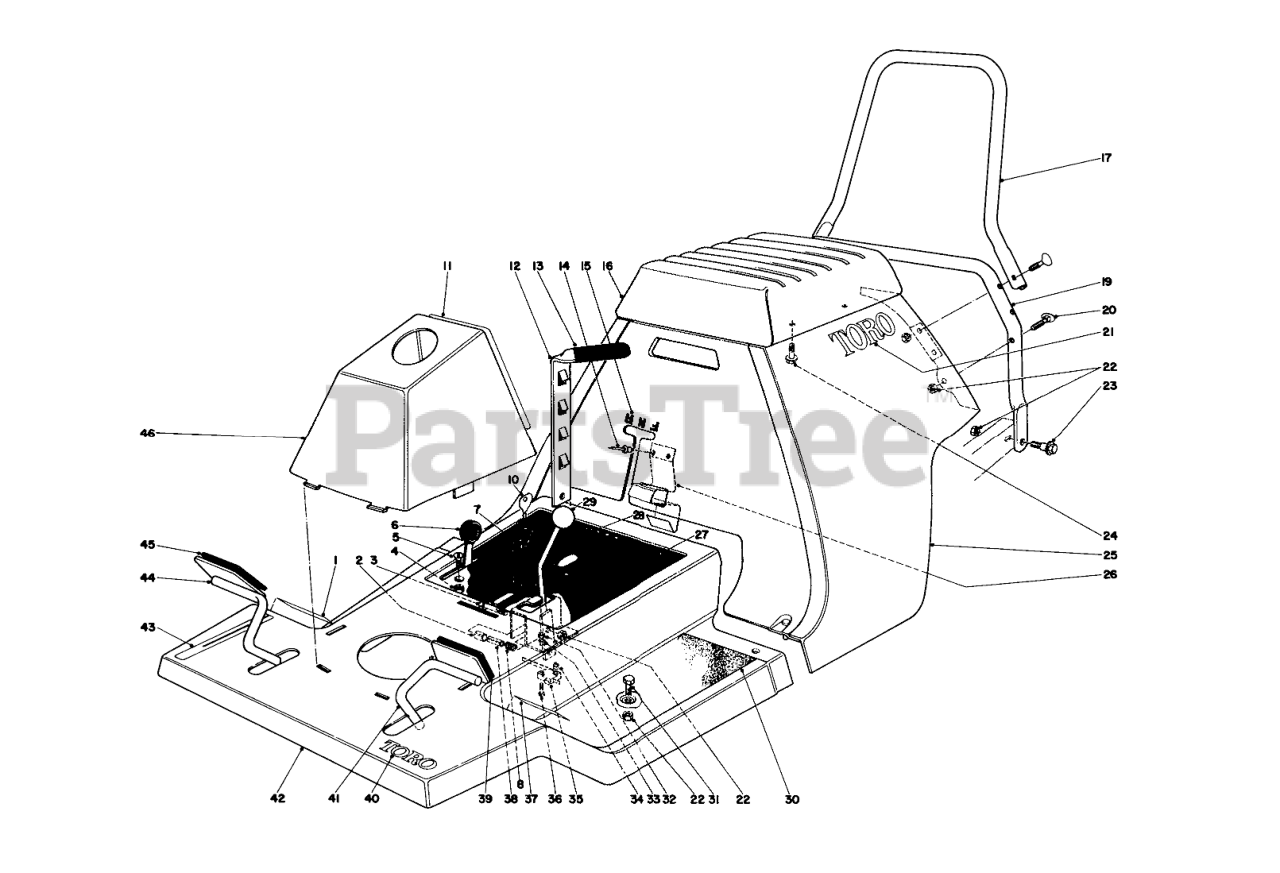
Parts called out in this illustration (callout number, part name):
1	Decal-Brake Pedal
2	Spacer
3	SCREW-HH
4	NUT-LOCK, SIDE
5	10-24X 1/2 PHILLIPS SCR
6	Throttle Control
7	Switch
8	Spring
10	Key
11	Decal
12	Lift-Vertical
13	Grip Handle
14	RIVET-BLIND
15	Decal Shift Pattern
17	Handle-Upper
19	Handle Lower
20	HANDLE SCREW
21	Decal
22	NUT-LOCK, CONE
23	SCREW-SHOULDER
24	SCREW-HHF
25	Rear Body
26	Spring Latch
27	Decal-Control Panel (Model 56525)
28	Deck Engagement Lever
29	KNOB-CONTROL
30	Hour Meter
31	SCREW-HH
32	NUT-LOCK, NI
33	WASHER
34	Spacer
35	MICRO SWITCH
36	SCREW-PPH
37	Decal Clutch Pedal
38	Spacer Split
39	Foot Pad Clutch
40	DECAL
41	Clutch Pedal
42	Body Front
43	Decal
44	Brake Pedal
45	Foot Pad Brake
46	Tower
